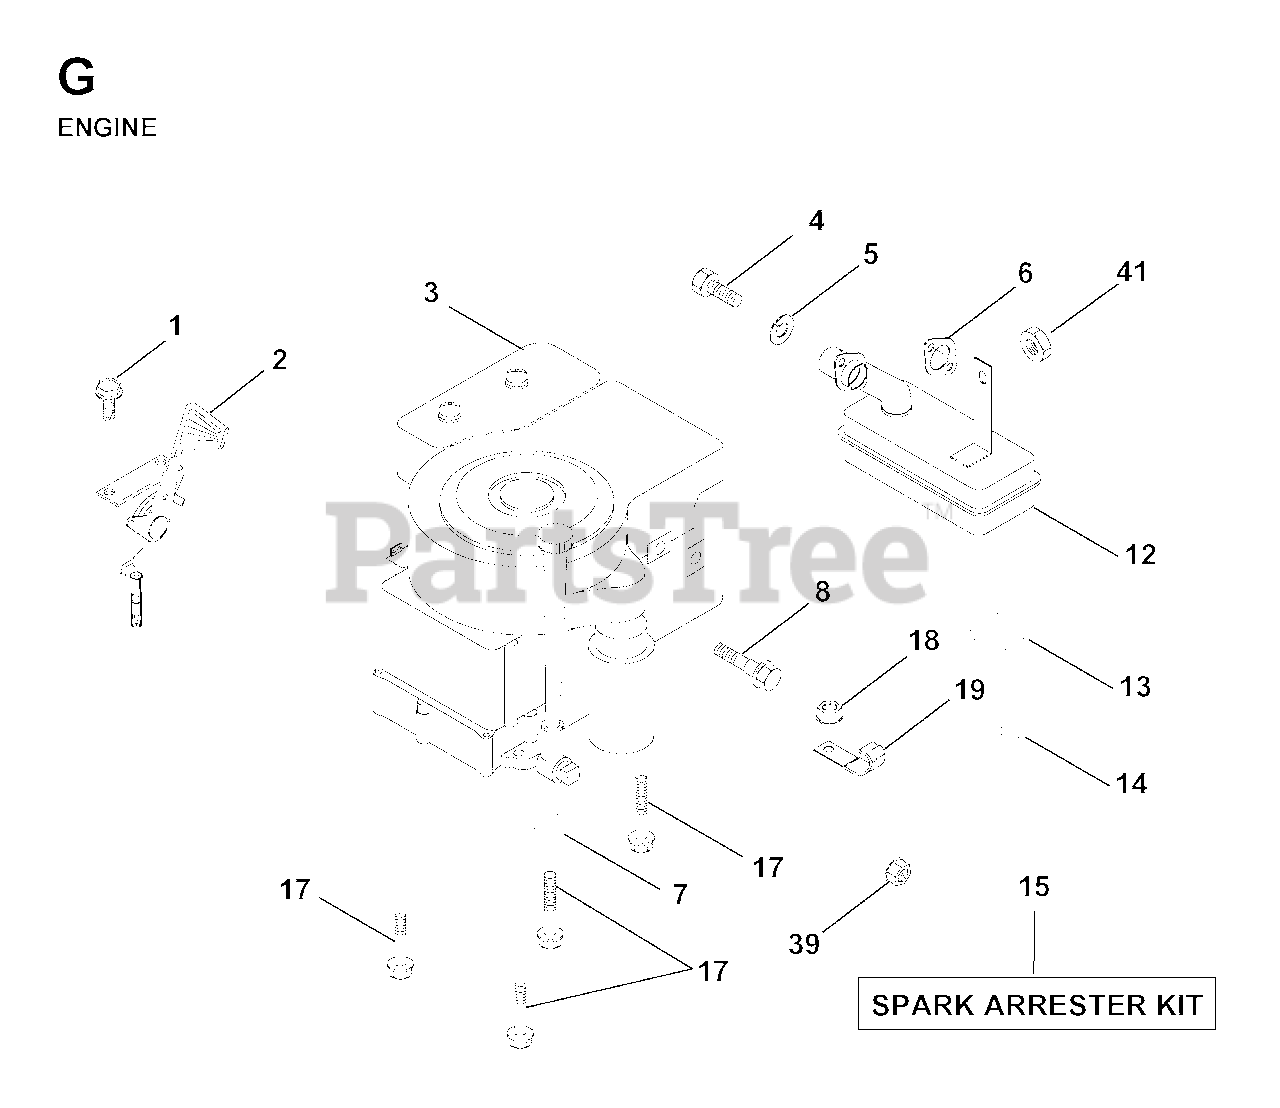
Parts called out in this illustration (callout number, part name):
2	CONTROL THROTTLE
5	LOCKWASHER
6	GASKET ENG
7	LOCKWASHER
8	SHOULDER BOLT ST
13	DEFL MUFFLER LTV
14	SCREW
15	ARRESTER SPARK (OPTIONAL)
17	SCREW LT
19	CLIP T
39	NUT FLANGE 1/4-20 STARTER NUT
41	NUT LOCK HEX FLANGE 5/16-18
